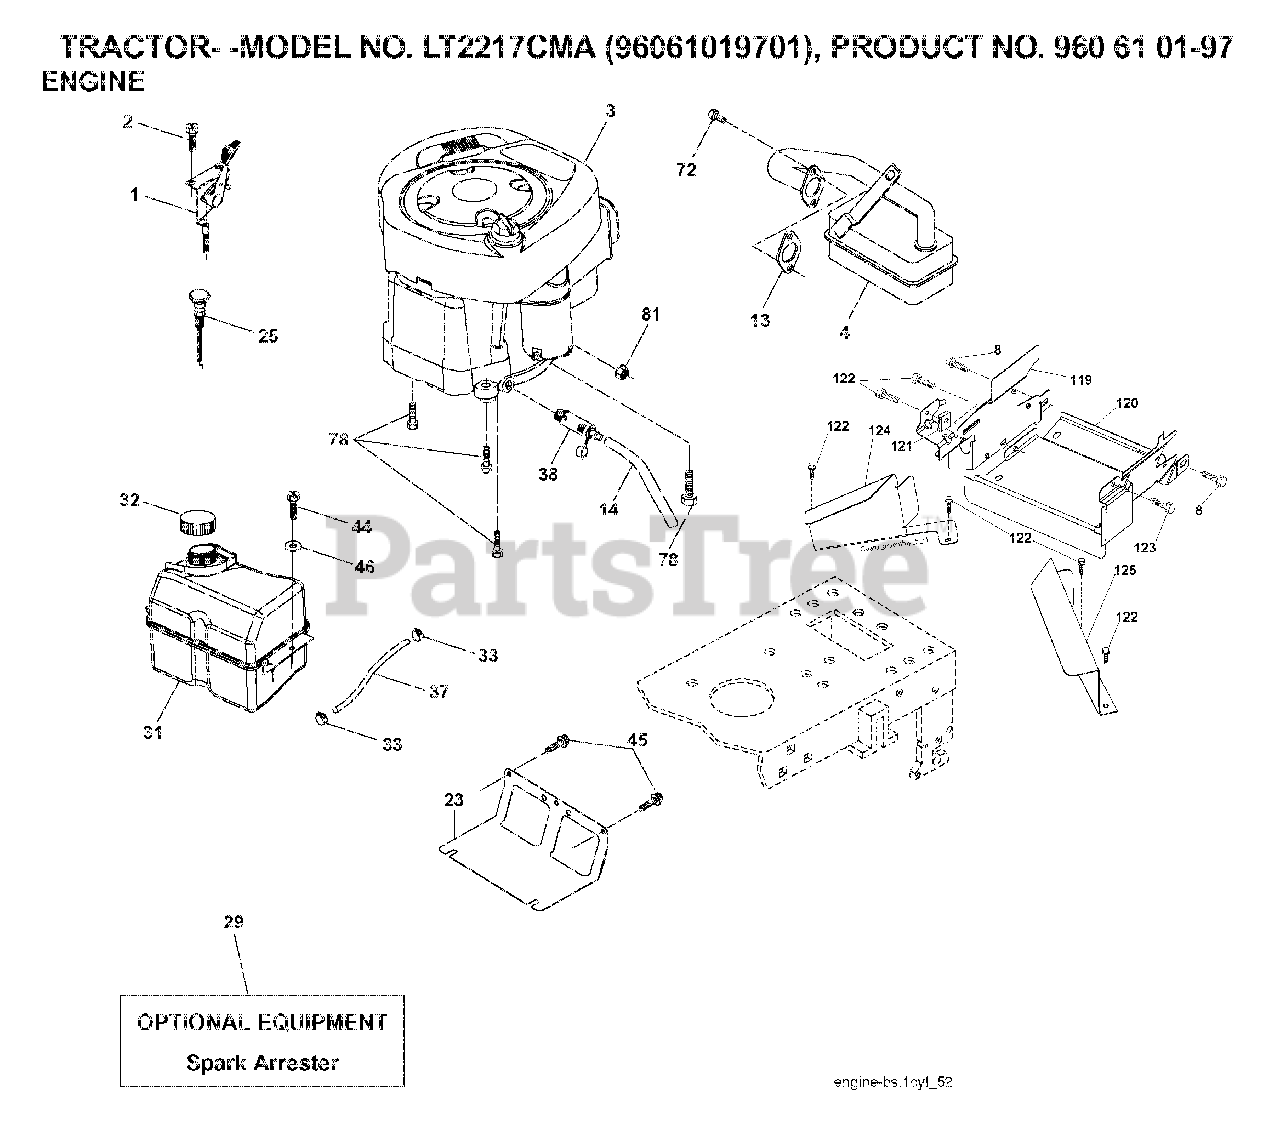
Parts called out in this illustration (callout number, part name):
1	CONTROL TH/CH FLAG
2	SCREW
8	BOLT, 5/16-18 X 1 3/4
13	REPL BY 532 27 22-93
14	TUBE, DRAIN OIL ASM.
23	SHEILD.BROWNING.DBR.GUARD
29	ARRESTER SPARK (OPTIONAL)
31	TANK FUEL
32	FUEL CAP
33	HOSE CLAMP
37	LINE.FUEL.20
38	PLUG DRAIN OIL EASY
44	SCREW HEXWSHR 1/4-20X3/4
45	SCREW, 3/8-16X3/4
72	SCREW.SOCKET HD.5/16-1
78	SCREW.3/8-16
81	NUT
122	SCREW.1/4-20X5/8
123	SCREW, 5/16-18 X 1/2
